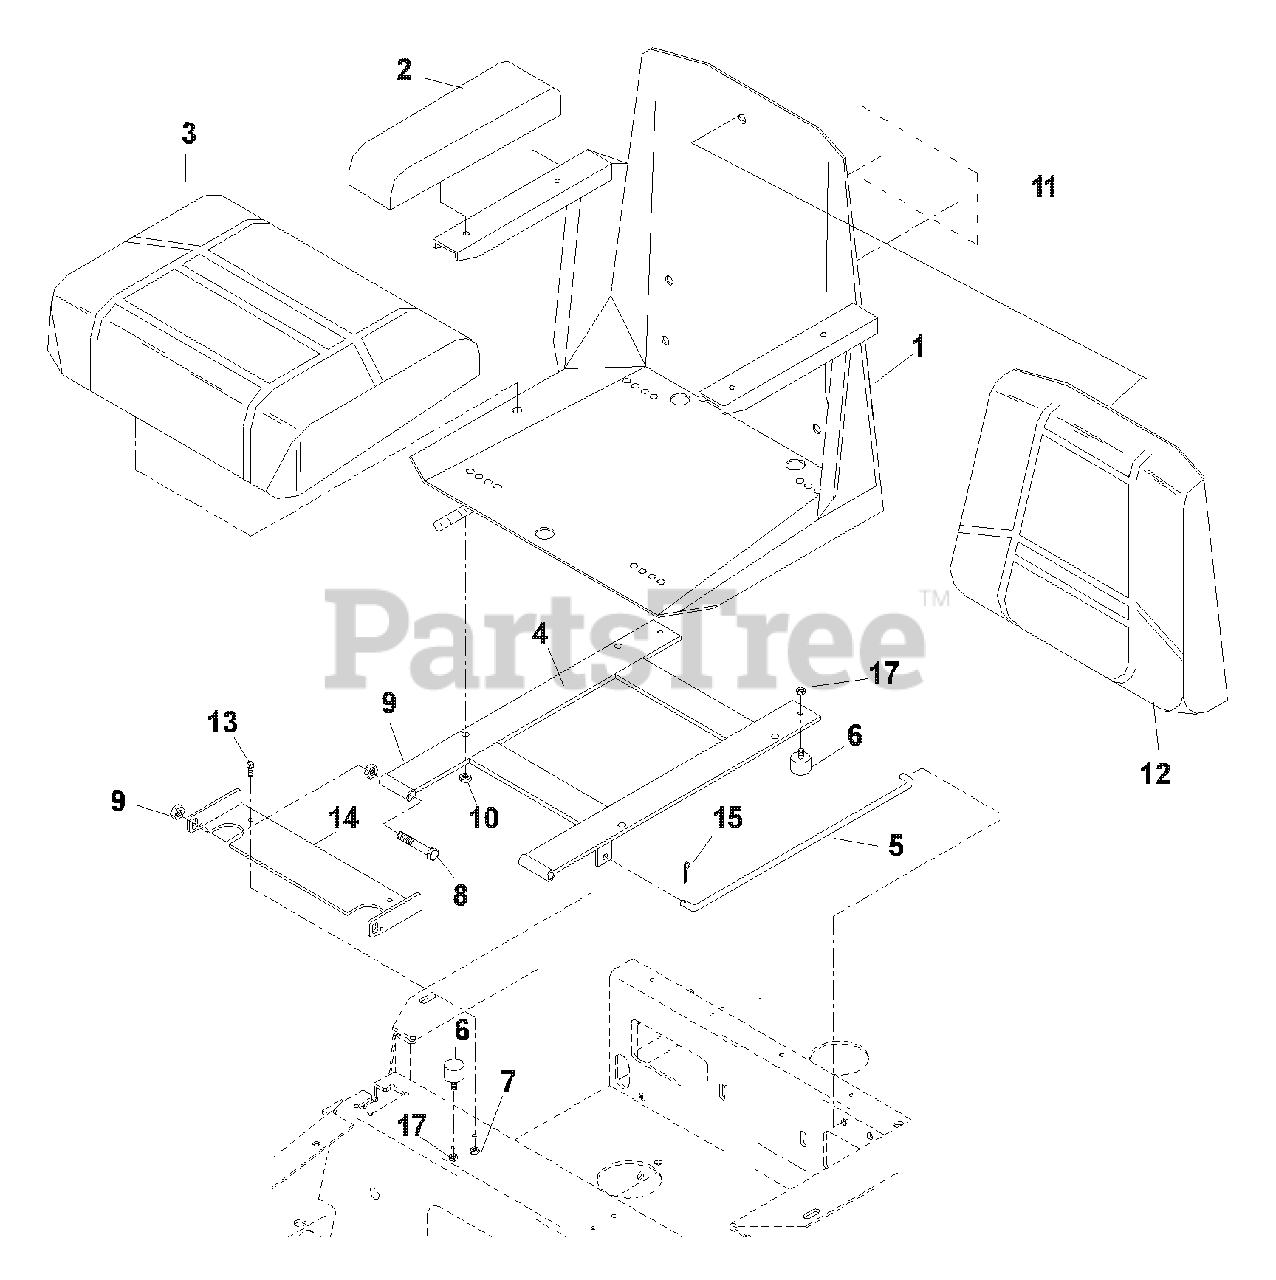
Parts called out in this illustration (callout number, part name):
1	SEAT, COMPLETE
2	ARM REST CUSHION
3	SEAT CUSHION W/SWITCH
4	SEAT MOUNT
6	STUD / PLATE MOUNT
7	1/4C LOCKNUT
8	HCS 3/8C X 3
9	NUT 3/8C CTR. LOCK
10	NUT 5/16C CTR. LOCK
11	DECAL, CROWN
12	SEAT BACK CUSHION
13	HCS 1/4C X 3/4
14	SEAT BKT. W/DECAL
15	COTTER PIN
17	NUT 1/4C NYLOC
